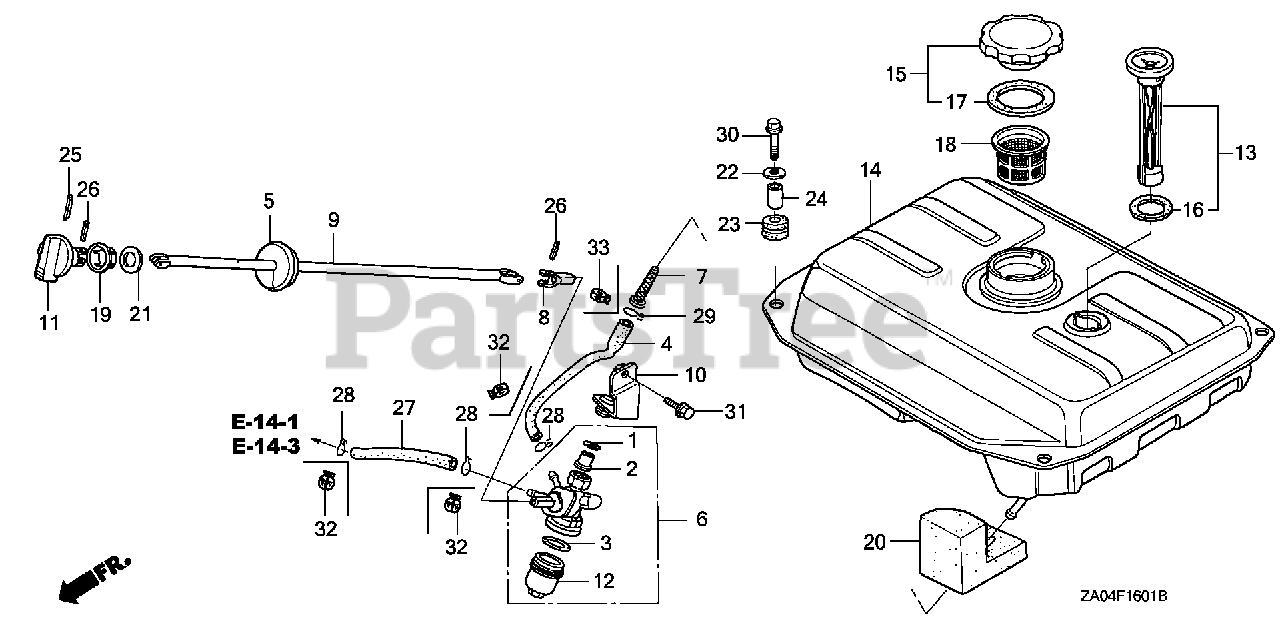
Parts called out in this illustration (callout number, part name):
1	O-RING (NOT AVAILABLE)
2	COLLAR, PETCOCK SETTING (NOT AVAILABLE)
3	GASKET, FUEL STRAINER CUP
4	TUBE, FUEL TANK
5	GROMMET, FUEL PUMP (NOT AVAILABLE)
6	PETCOCK ASSY.
7	FILTER, FUEL
8	JOINT, PETCOCK CONTROL
9	SHAFT, PETCOCK CONTROL
10	STAY, PETCOCK
11	KNOB, PETCOCK CONTROL
12	CUP, FUEL STRAINER
13	METER, FUEL
14	TANK, FUEL *NH105* (MAT BLACK)
15	CAP, FUEL FILLER
16	GASKET C, FUEL METER
17	GASKET, FUEL FILLER CAP
18	FILTER, FUEL
19	BUSH, PETCOCK SHAFT
20	RUBBER A, SEPARATOR SEAL
21	WASHER, THRUST (18.6MM)
22	WASHER, TANK CUSHION
23	RUBBER, TANK CUSHION
24	COLLAR, TANK CUSHION
25	PIN, SPLIT (2.0X35)
26	PIN, SPRING (2.5X16)
27	BULK HOSE, FUEL (4.5X3000) (4.5X75)
28	CLIP, TUBE (B8)
29	CLIP, TUBE (B10)
30	BOLT, FLANGE (6X22)
31	BOLT, FLANGE (6X10)
